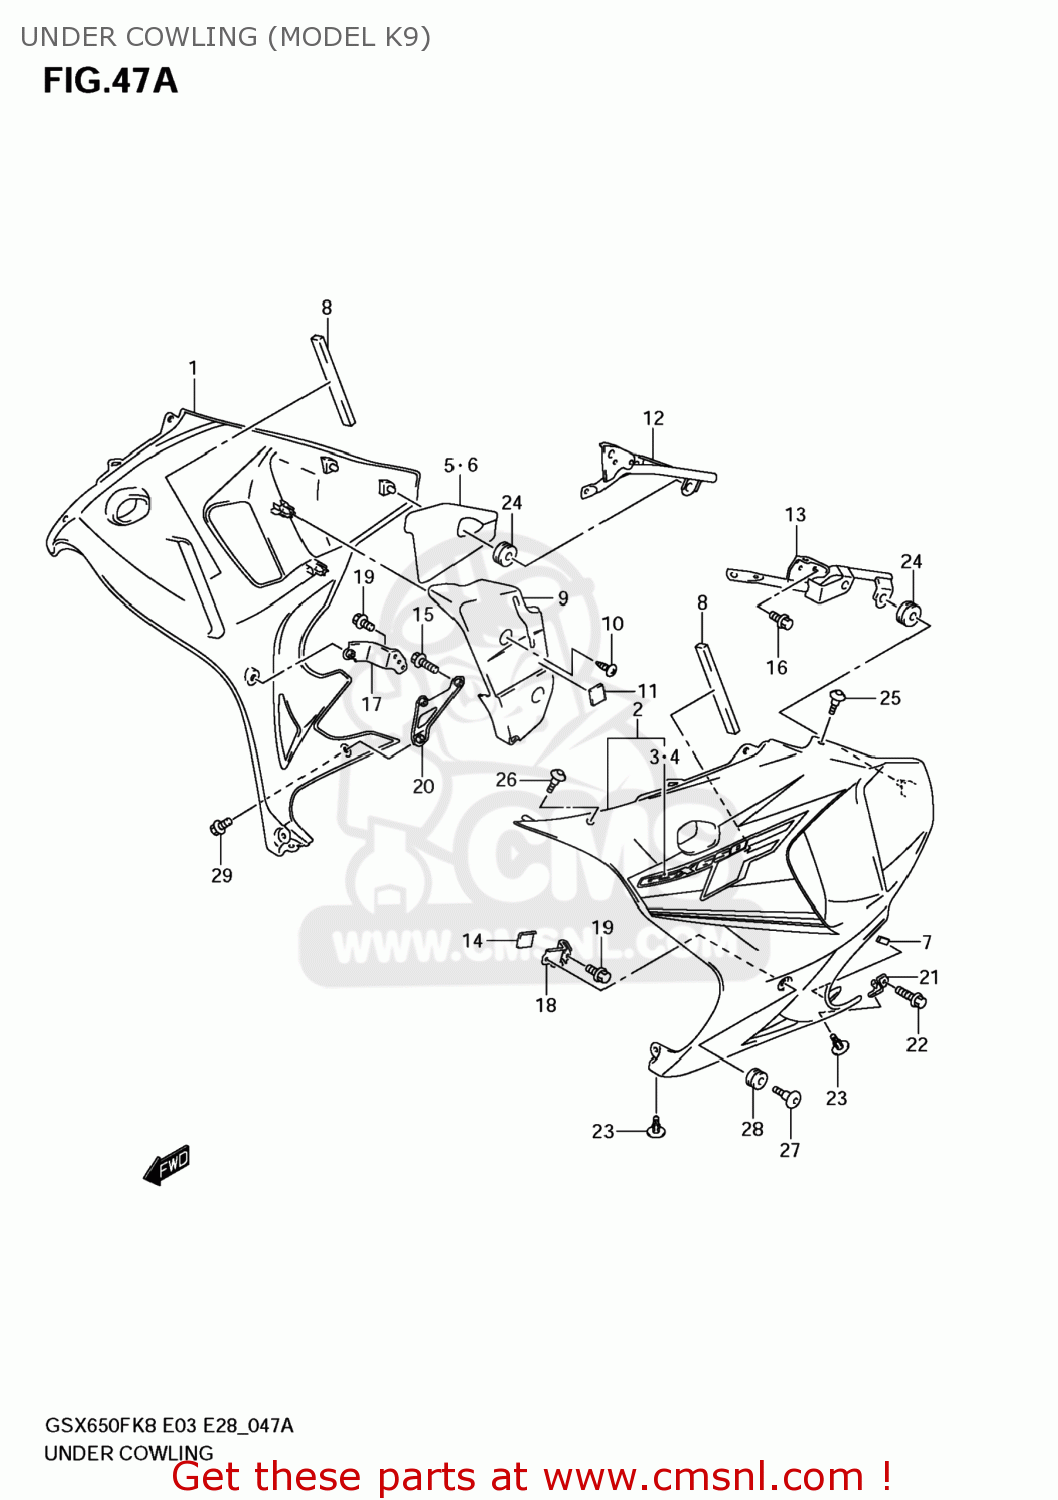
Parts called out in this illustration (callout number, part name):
1	COWLING,UNDER,R
2	COWLING,UNDER,L
3	TAPE,UNDER COWL,R
4	TAPE,UNDER COWL,L
5	SHIELD,UNDER COWL HEAT,R
6	SHIELD,UNDER COWL HEAT,L
7	CUSHION,LICENSE PLATE
8	CUSHION,UNDER COWLING
9	PROTECTOR,COWLING UNDER,R
10	SCREW
11	CUSHION,UNDER COWL ENG,R NO.1
12	BRACKET,COWLING FITTING,R
13	BRACKET,COWLING FITTING,L
14	PROTECTOR,COWLING UNDER
15	BOLT
16	BOLT
17	BRACKET,UNDER COWLING FR,R
18	BRACKET,UNDER COWLING FR,L
19	BOLT
20	BRACKET,UNDER COWLING LWR,R
21	BRACKET,UNDER COWLING LWR,L
22	BOLT
23	CLIP
24	CUSHION
25	SCREW(5X16)
26	SCREW(5X13)
27	SCREW(6X20)
28	CUSHION
29	SCREW(6X12)
